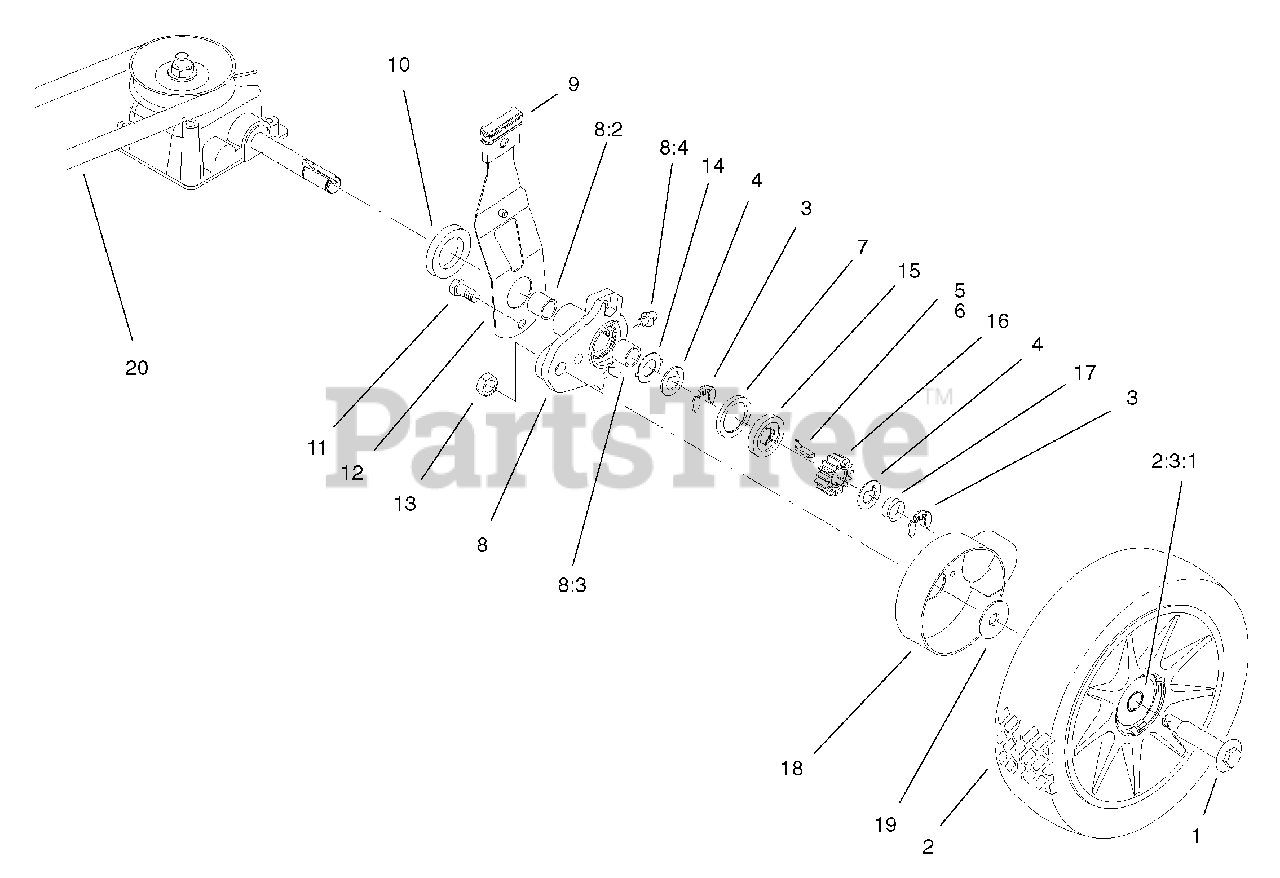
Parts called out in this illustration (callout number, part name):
1	Bolt-Shoulder
2	Wheel & Tire ASM
2:3	Wheel & Tire ASM
3	Ring-Klip
4	Washer-Thrust, Keyed
5	Key-Rocking, LH
7	Ring-Friction
8	Rear Height Adjustment Arm ASM
8:4	Fitting-Zerk
9	Knob-Lever, Height Adjustment
10	Spacer-Axle Shaft
12	Rear Spring Arm ASM
14	Washer-Arm, Pivot
15	Washer-Clutch
16	Gear-Pinion
17	Spring-Compression
18	Cover-Wheel
19	Washer-Stepped
